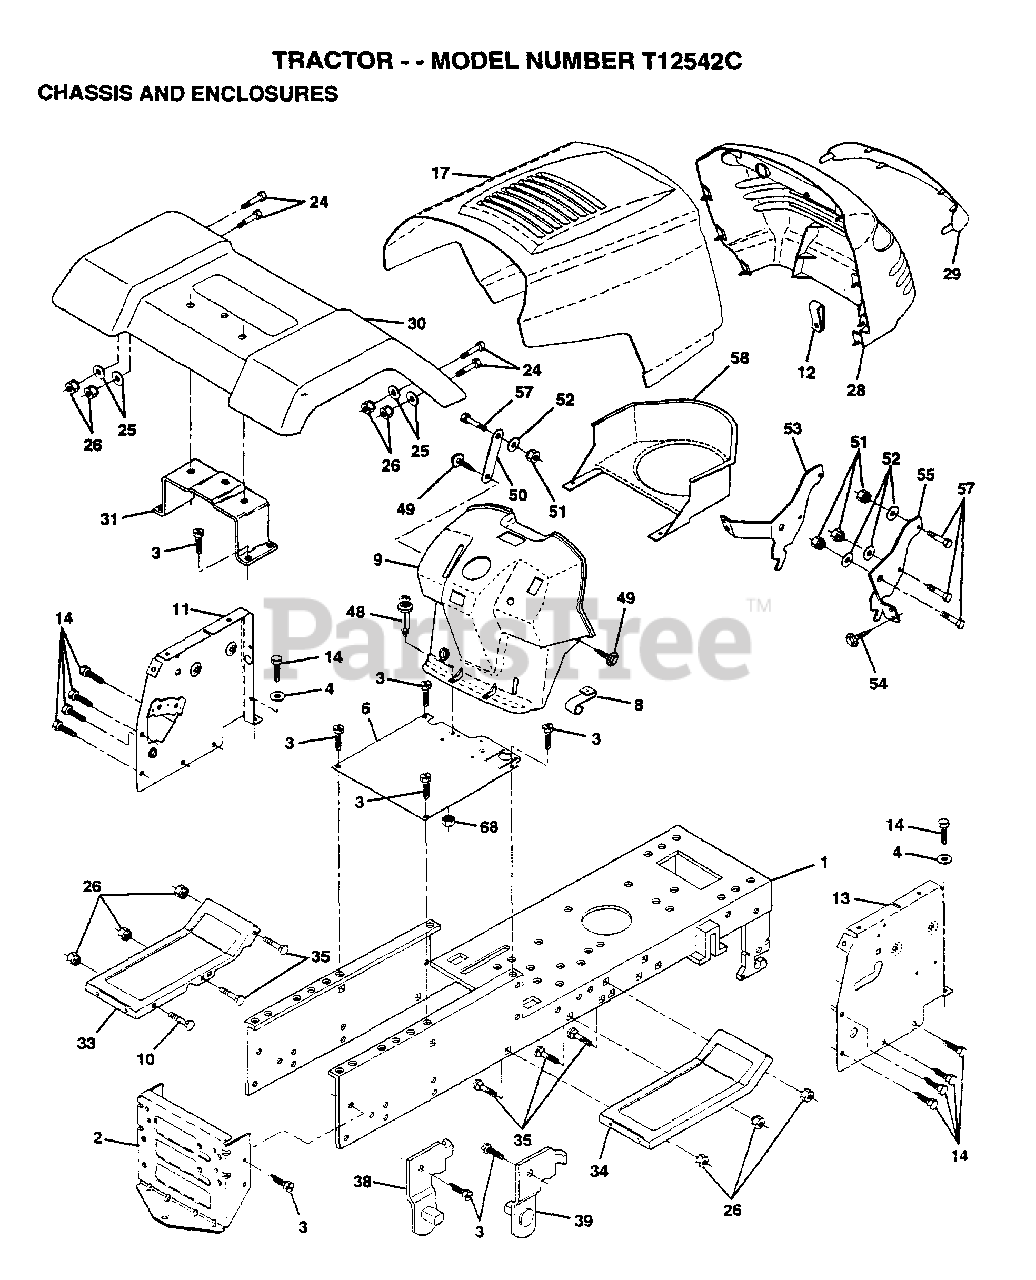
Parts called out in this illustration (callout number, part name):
1	CHASSIS.WLD.11GA
3	SCREW
4	WASHER
8	"CLIP,INSULATOR"
11	PANEL.DASH.LH.
12	CLIP.TINNERMAN
13	PANEL.DASH.RH
14	SCREW LT
24	BOLT
25	WASHER
26	NUT
29	LENS GRILLE
31	BRKT FENDER
33	FOOTREST.LH.PERF.
34	FOOTREST.RH.PERF.
35	BOLT
38	BRACKET ASM LH
39	BRACKET ASM RH
48	RIVET.PUSH.PLATE
49	SCREW HEX CRT
50	BRACE SUPT DASH
51	NUT
52	WASHER
53	BRACKET.GRILLE.LH
55	BRACKET.GRILLE.RH
58	DUCT AIR 12-15H
68	NUT
